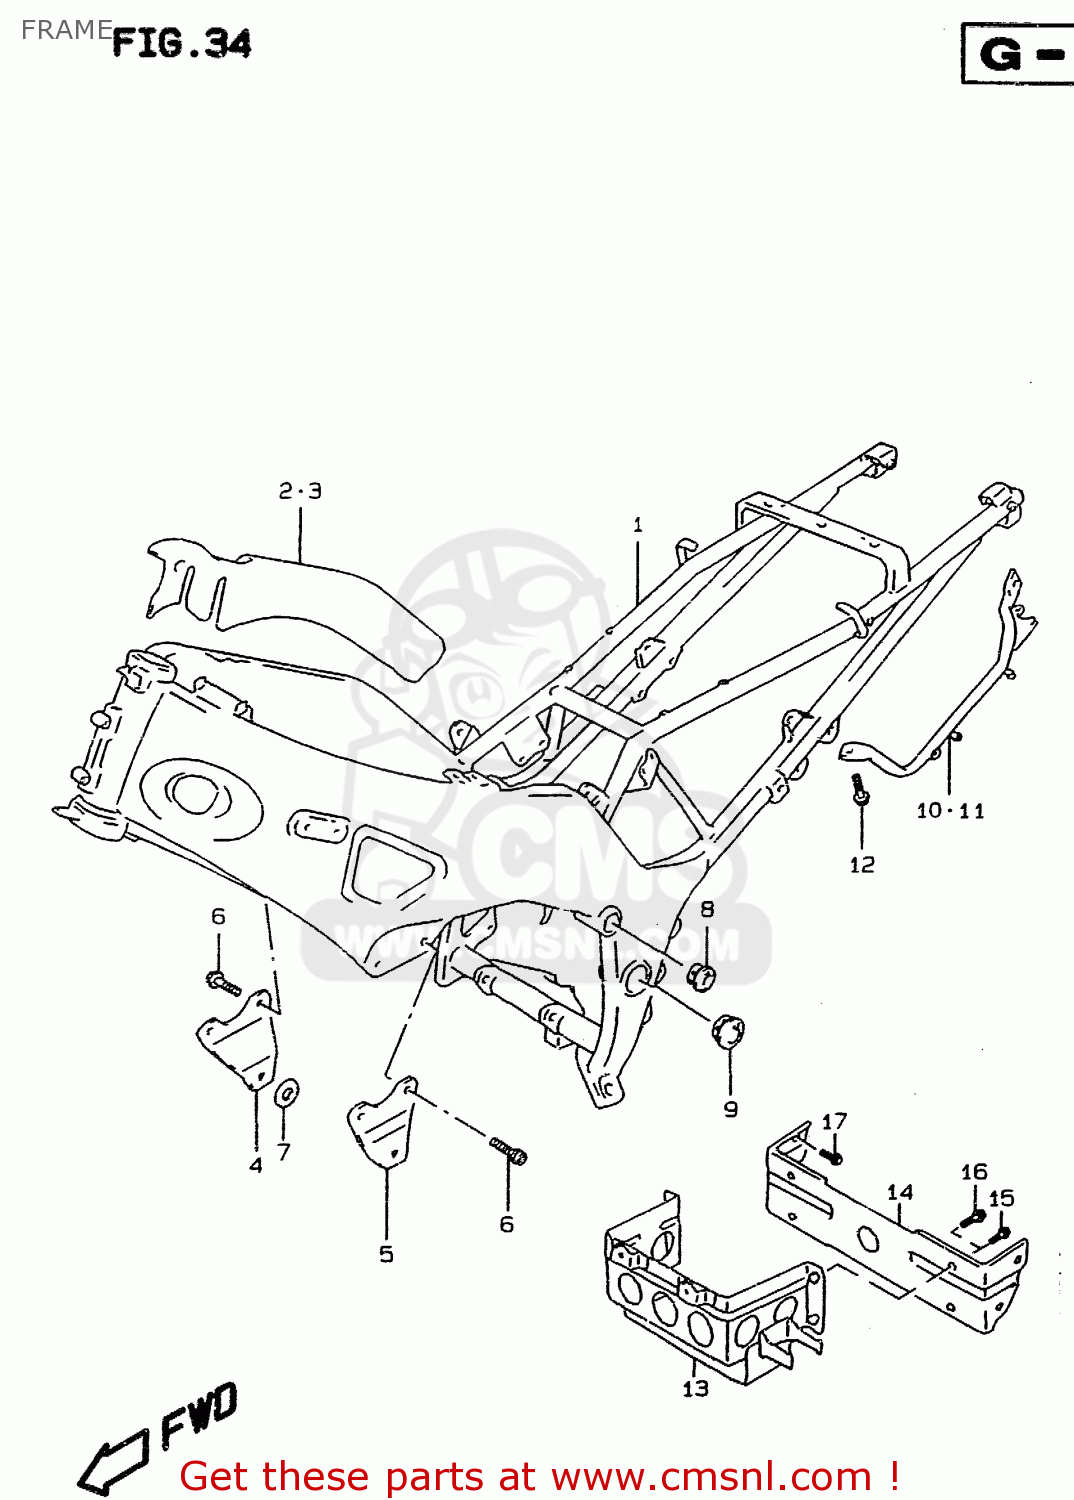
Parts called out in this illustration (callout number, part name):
1	FRAME COMP
2	SHIELD,FRAME HEAT,RIGHT
3	SHIELD,FRAME HEAT,L
4	PLATE,ENG MTG,R
5	PLATE,ENG MTG,L
6	BOLT
7	WASHER(10.5X38X1.6)
8	CAP,FRAME BOSS,L
9	CAP,FRAME PIVOT
10	GRIP, REAR RH
11	GRIP,RR,L
12	BOLT
13	HOLDER,BATTERY
14	BRACKET,BATTERY HOLDER
15	SCREW 6X12
16	BOLT
17	BOLT
